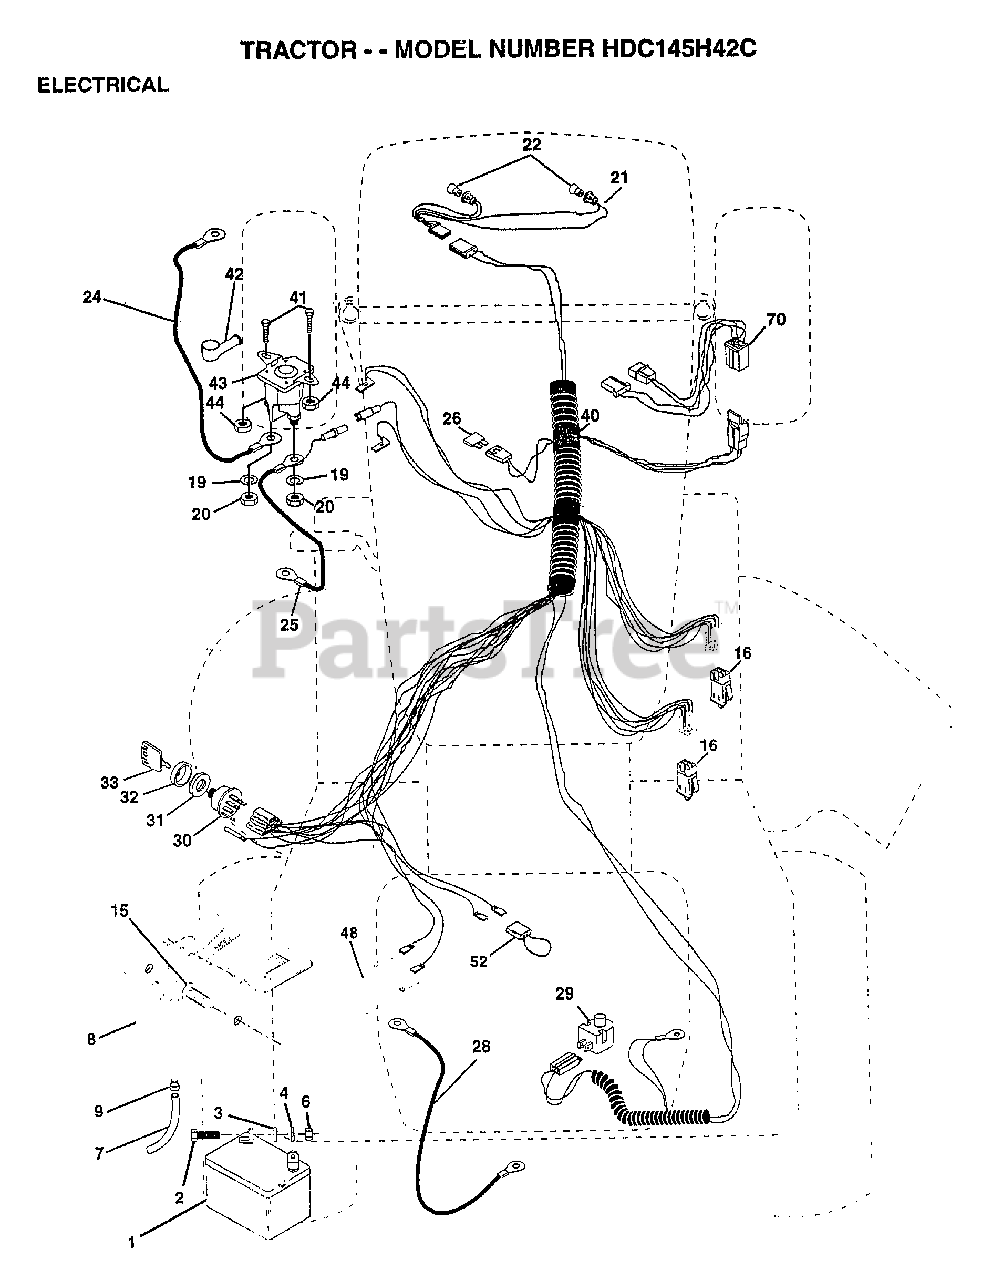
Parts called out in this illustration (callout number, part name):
2	BOLT LT
3	WASHER
4	LOCKWASHER
7	TUBE T
8	"CASE,BATTERY.MECH"
9	HOSE CLAMP T
15	FASTNER.SNAP-IN
16	SWITCH INTERLOCK
20	NUT
21	"HARNESS,LIGHT SOC"
22	HEADLAMP BULB
24	"CABLE T, BATTERY"
25	CABLE.BTRY.6GA.RD
26	FUSE HYT
28	CABLE T
29	SWITCH SEAT
30	SWITCH IGN 4POS
31	NUT IGNITION
32	COVER KEY SWITCH
33	KEY
40	HARNESS-IGNITION
41	BOLT HXHD FIN
44	NUT HXKEP 1/4X20
48	ADAPTER AMMETER
52	PROTECTION LOOP
70	HARNESS.ENG.DUAL
